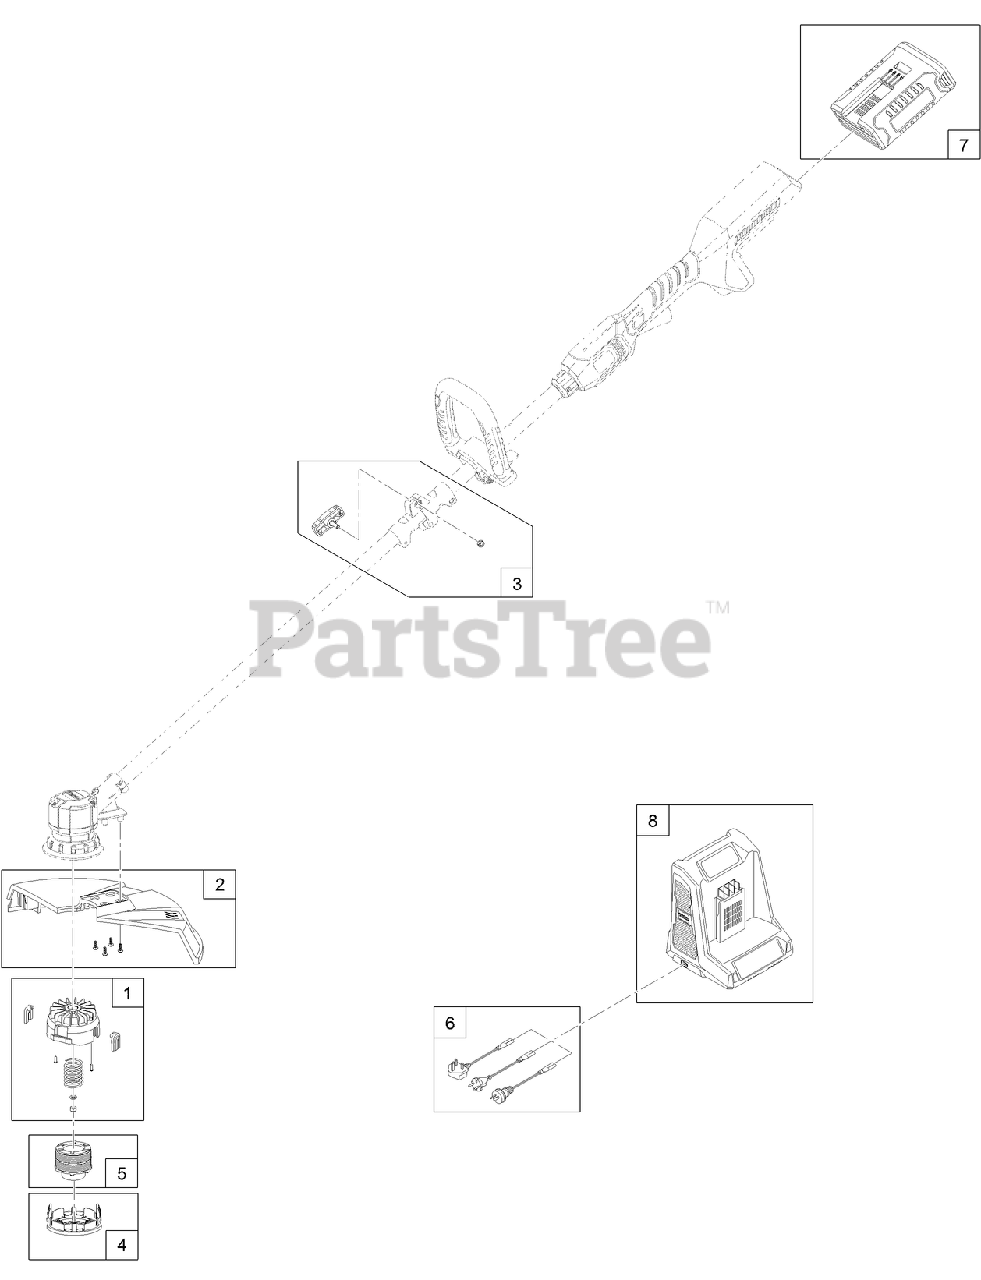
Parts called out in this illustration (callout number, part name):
1	HEAD-FEED, BUMP
2	SHIELD-GRASS
3	SHAFT CONNECTION HARDWARE KIT
4	RETAINER-CAP, SPOOL
5	3-PACK DUAL-LINE TRIMMER SPOOL
6	CORD SET
7	BATTERY-40V MAX
8	CHARGER-BATTERY, 40V MAX
